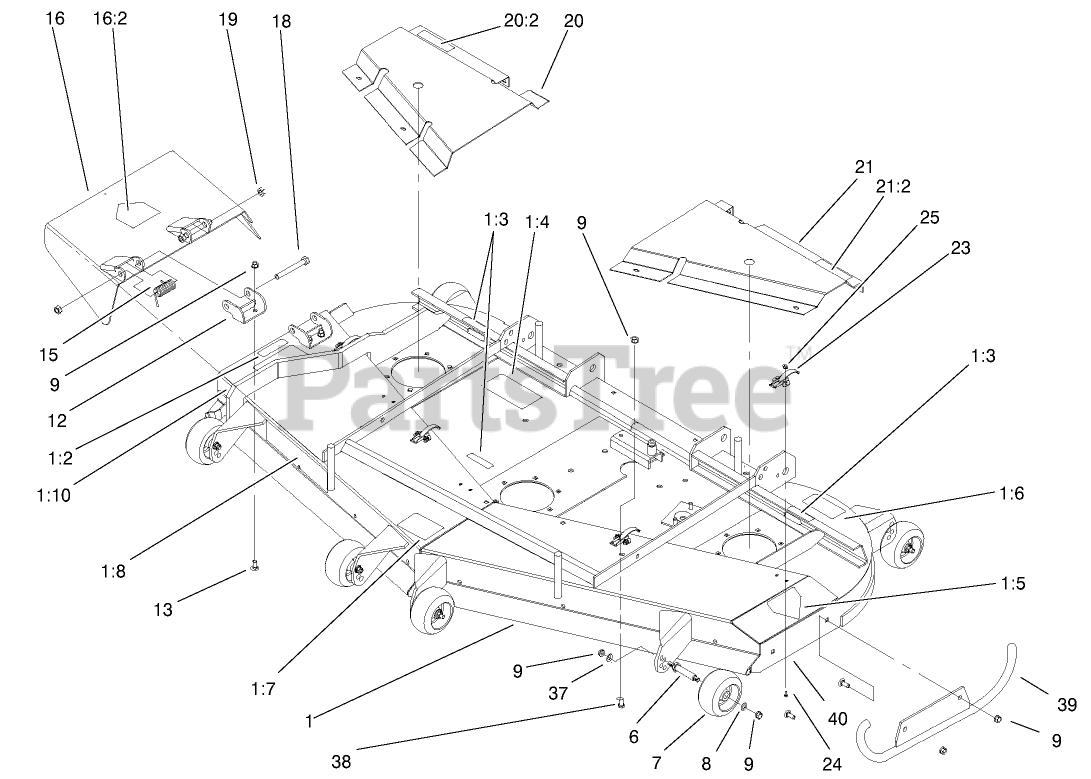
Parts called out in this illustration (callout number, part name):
1	OBS DECK ASM W/DECALS
1:2	DECAL-DANGER
1:3	DECAL-COVER, MISSING
1:4	DECAL-ROUTING, BELT
1:5	DECAL-DANGER
1:6	DECAL-TORQUE, BLADE BOLT
1:7	DECAL-WHEEL, GAGE
1:8	DECAL-DECK
1:10	DECAL-DANGER, THROWN OBJECT
6	SPACER
7	WHEEL-GAGE
8	Washer
9	NUT-HHF, WHIZ
12	HINGE BRACKET ASM
13	SCREW-CARR
15	SPRING
16	DEFLECTOR ASM
16:2	DECAL-DANGER
18	SCREW-HH
19	NUT-HEX
20	RH COVER W/DECAL ASM
20:2	DECAL-DANGER
21	LH COVER W/DECAL ASM
21:2	DECAL-DANGER
23	CLAMP-SLOTTED
24	SCREW-HWH
25	NUT-LOCK, FLANGE
37	WASHER-BELLEVILLE
38	SCREW-HH
40	SCREW-CARR
